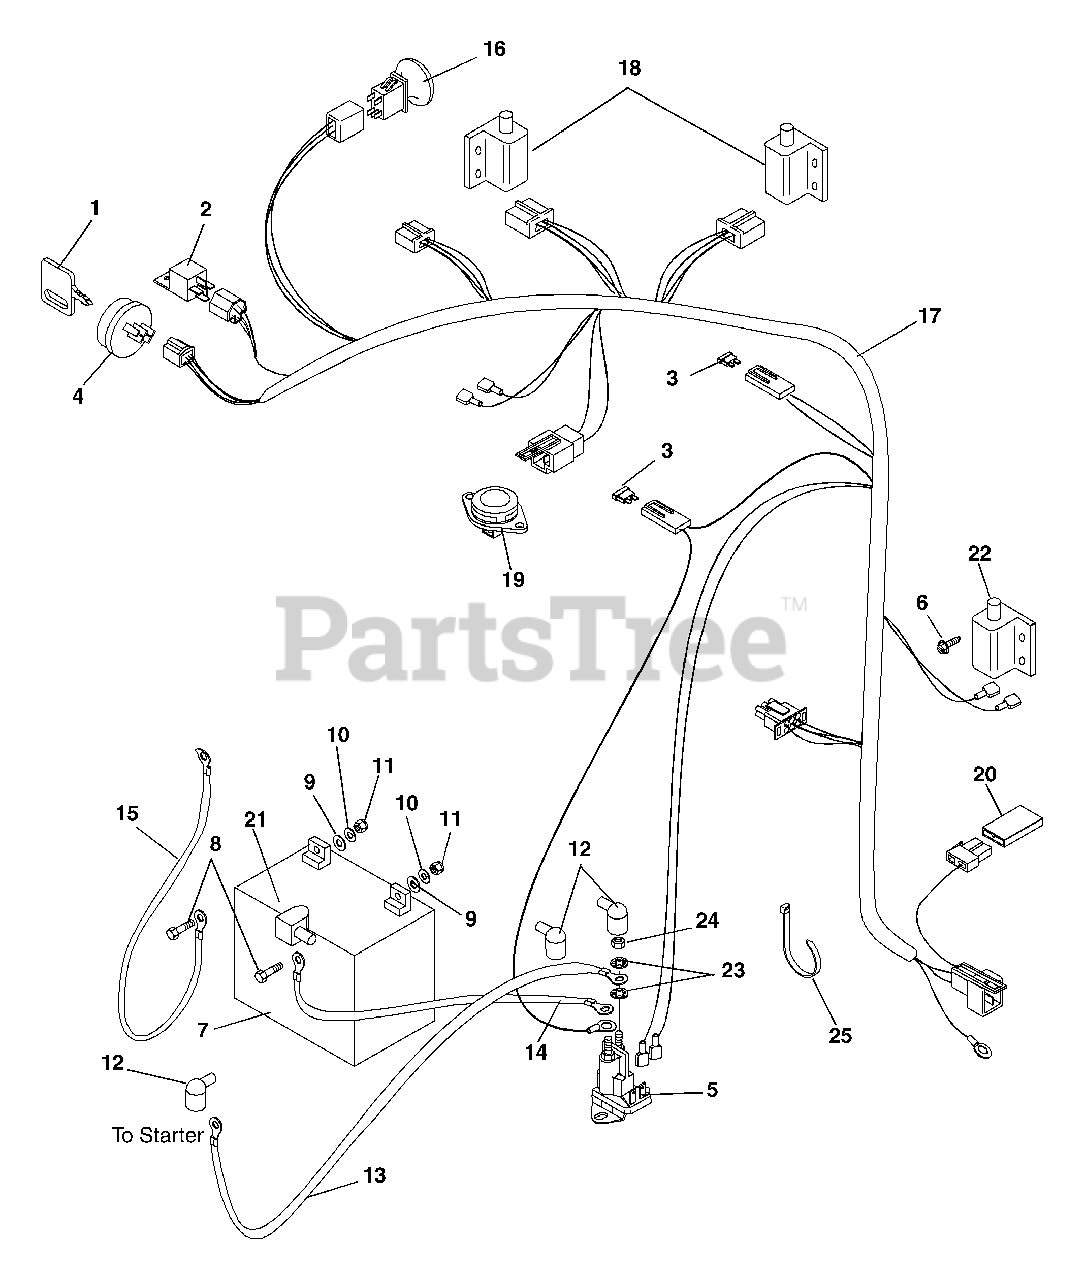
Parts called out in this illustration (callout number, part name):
1	KEY -W/CAP
2	RELAY
3	FUSE-25 AMP ATC TYPE
4	KEY SWITCH
5	SOLENOID
6	@SCR-TAP 10-24X.50 HWH TR YWZC
7	BATTERY, 300 CCA 10U1L
7	BATTERY W/ TUBE
8	@BLT-HEX .25-20X.75 GR5 YWZC
9	@WSHR-FL-STL.281X.62X.065 YWZC
10	@WSHR-LK .25X.062 REG YWZC
11	@NUT-HEX .25-20 YWZC
12	BOOT, EYELET TERMINAL
13	START CABLE 22"
14	STARTER CABLE 13"
15	GROUND CABLE .31X22.00X.31
16	SWITCH, CLUTCH
17	WIRE HARNESS - ZOOM 6 PIN
18	SWITCH- DOUBLE POLE N.O./N.O.
19	SWITCH- SNAP MTG N.O.
20	DIODE, CONNECTOR SHELL
21	INSULATOR
22	SWITCH, INTERLOCK NC
23	WSHR-LOCK INT .31 YWZC
24	NUT-JAM .31-24 YWZC
25	CABLE TIE LG 5-1/2
